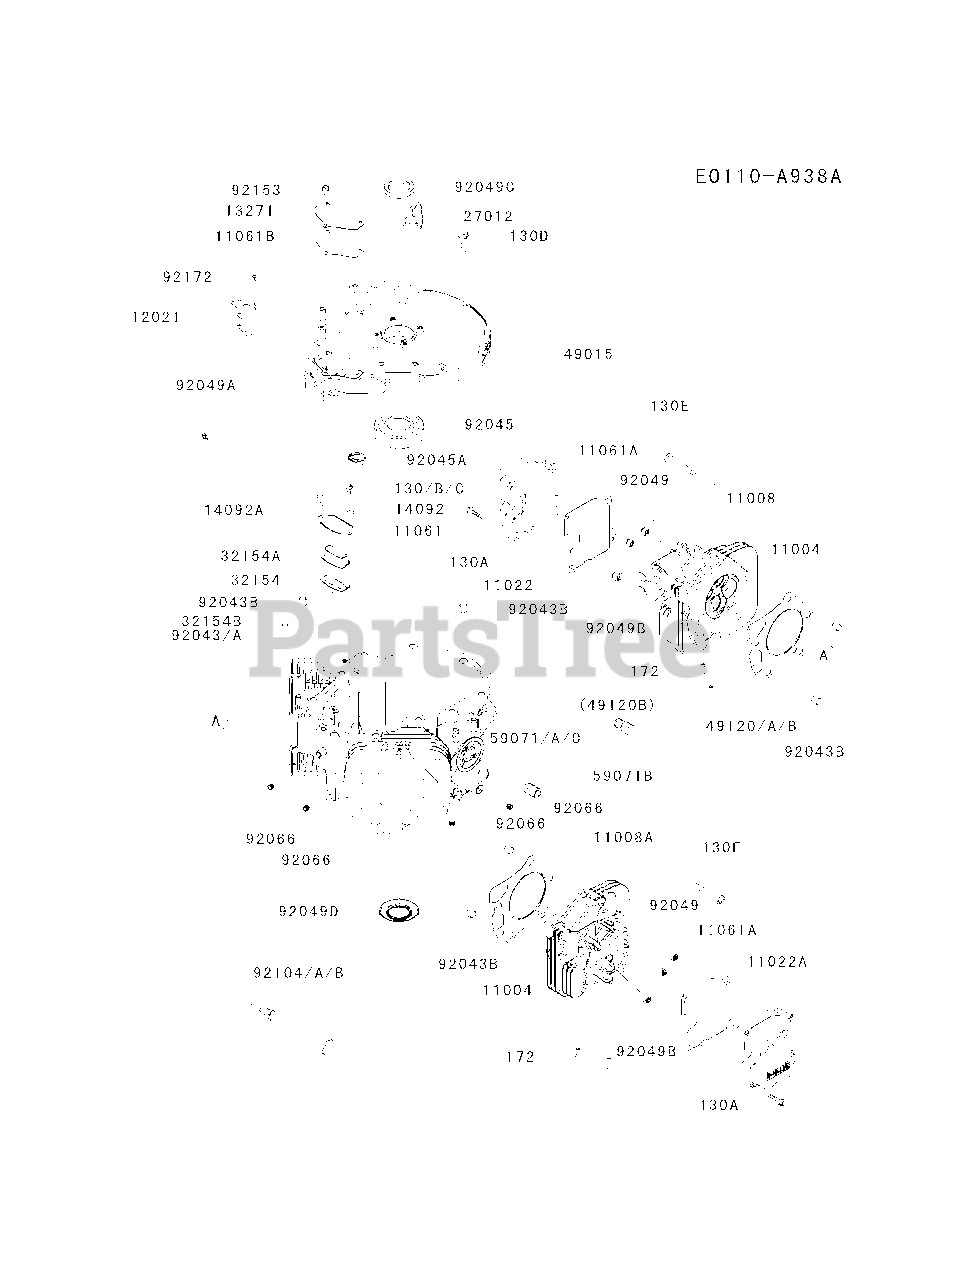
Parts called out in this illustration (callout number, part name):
130A	BOLT-FLANGED,6X30
130B	BOLT-FLANGED,6X16
130D	BOLT-FLANGED,10X40
130E	BOLT-FLANGED,10X65
172	BOLT-STUD,8X22
